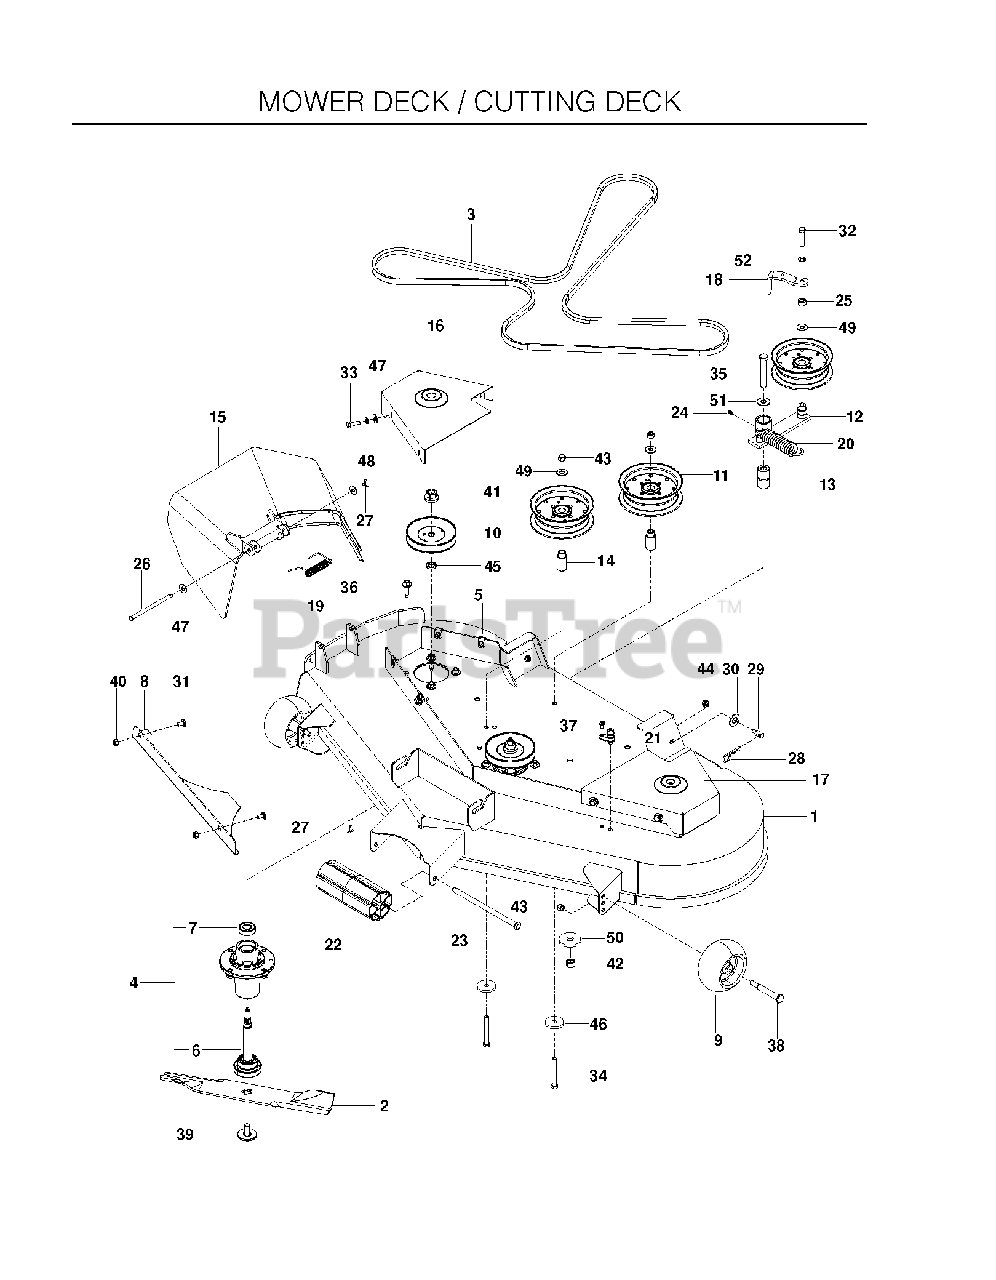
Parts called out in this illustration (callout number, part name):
1	DECK W/DECALS - RAM 48
2	BLADE, 16-1/4" FUSION
3	BELT, DECK
4	HOUSING ASM
6	GREASABLE MANDREL SHAFT
7	BEARING, BALL
8	CONFINEMENT PLATE 48" BLK
10	PULLEY MANDREL
11	PULLEY, IDLER
12	IDLER ARM
13	PIVOT BUSHING
14	IDLER BUSHING
15	DISCHARGE CHUTE 48"
16	BELTSHIELD - R.H. BLUE
17	BELTSHIELD - L.H. BLUE
18	GUIDE, BELT
19	SPRING - TORSION
21	PORT.WASHOUT
22	NOSEROLLER 48"
23	NOSE ROLLER ROD
24	ZERK
26	PIN-CLEVIS 5/16 DIA X 5.19 ZD
27	COTTER PIN 1/8 X 3/4
28	HAIRPIN #4
29	STUD.FASTNER.W/D.ANTI-
30	U-CLIP 5/16-18 NUT RETAINER
31	CARRIAGE BOLT 5/16C X 5/8"
32	HCS 3/8CX 1 3/4
33	HCS 5/16C X 1
34	HCS 3/8C X 3
35	HCS 1/2C X 3 1/4
37	BOLT 1/4-20 X 1/2 HWST
38	SHOULDER BOLT 1/2X2-5/8 ZD SPE
39	BLADE BOLT ASSY-7/16"
40	NUT 5/16 NYLOC
41	LOCKNUT - 9/16
42	NUT 1/2-13 HEX NYLOC ZD
43	NUT 3/8-16 NYLOC
44	5/16-18 NYLOC FLANGE NUT
46	SPINDLE WASHER
47	WASHER 5/16 FLAT
48	WASHER 5/16 LOCK
49	WASHER 3/8 FLAT
50	WASHER, SUPPORT
51	WASHER 1/2 FLAT
52	SLW 3/8 STD
